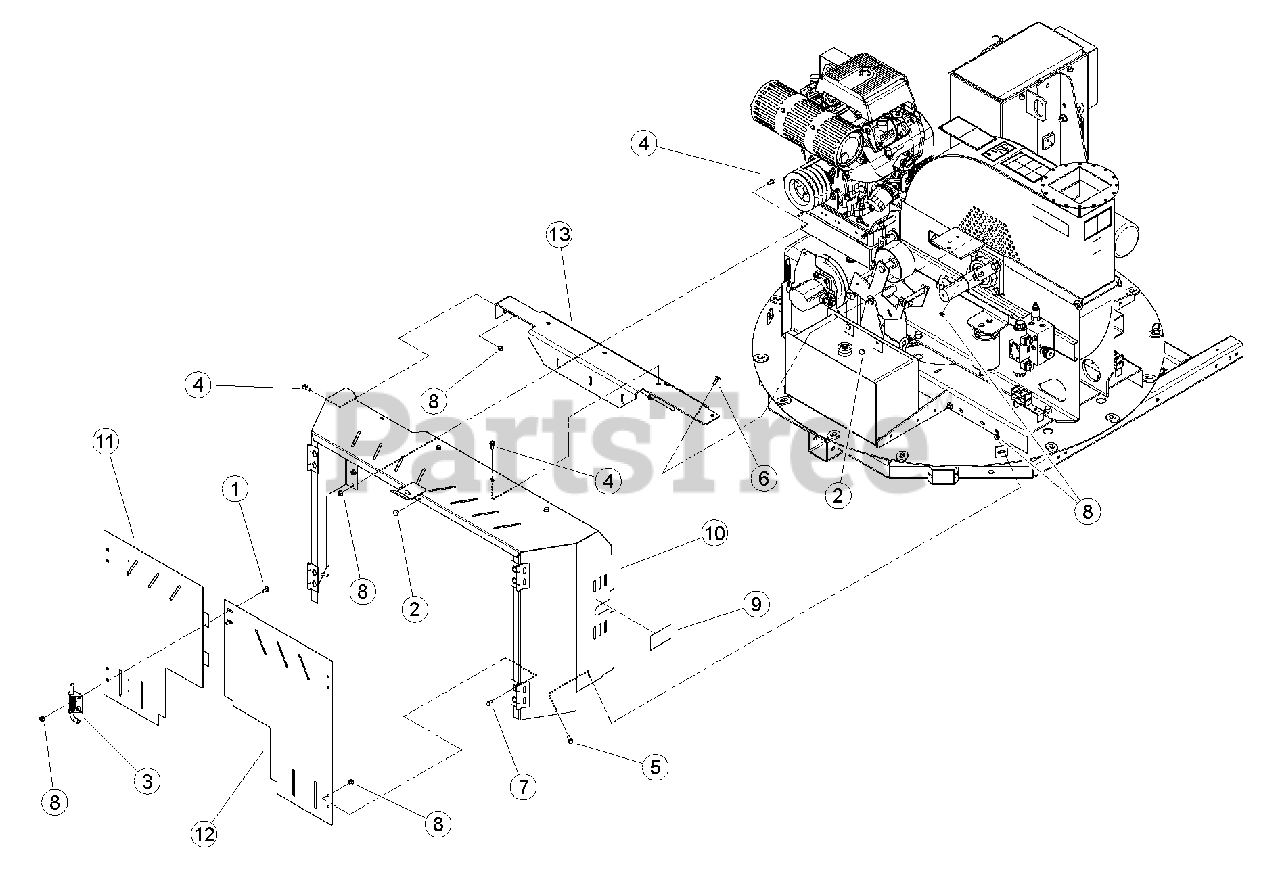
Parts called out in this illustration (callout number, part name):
1	BOLT, 5/16-18 X 3/4 CRG SN GR5
2	BUMPER, RUBBER
3	LATCH, RH HINGE
4	BOLT, 5/16 X 3/4 FLANGE NC
5	BOLT, 5/16 X 1 FLANGE NC
6	BOLT, 5/16 X 1" GR5 CRG ZP
7	BOLT, 5/16 X 5/8 GR5 CRG ZP
8	NUT, 5/16-18 NYLOCK-FLANGE
9	DECAL, FEED SPEED
10	WELDMENT, BELT SHIELD FRAME
11	WELDMENT, 8" LEFT DOOR
12	DOOR, 8" RIGHT
13	WELDMENT, ENGINE TIE
